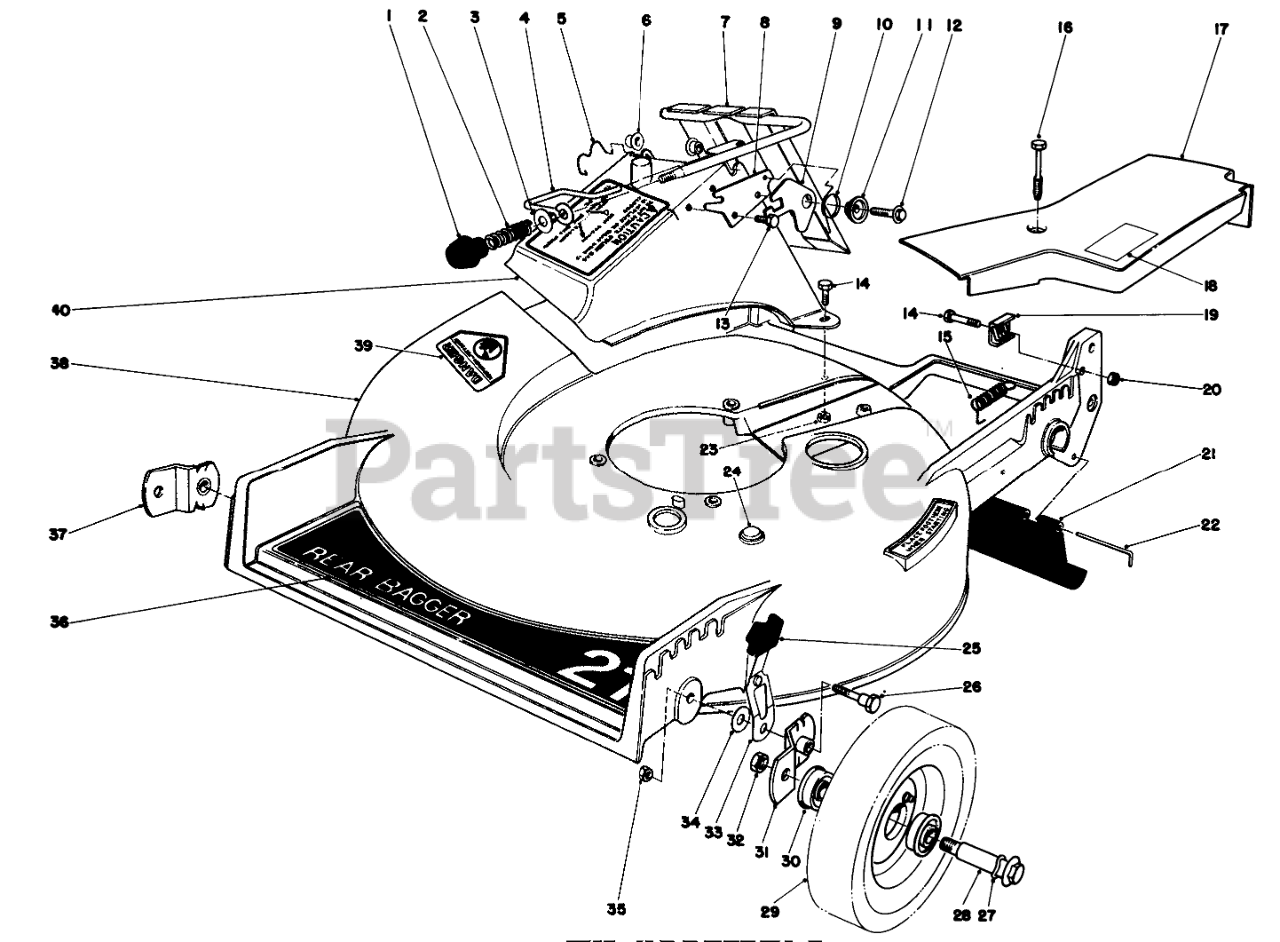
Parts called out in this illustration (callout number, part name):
2	Spring Compression
3	WASHER-FLAT
4	DOOR LATCH
5	DOOR RETAINER
6	BUSHING-NYLON
7	DOOR & HANDLE WA
8	DOOR LATCH PLATE
9	Latch-Door
10	Spring-Torsion
11	Latch Spacer
12	Screw
13	SCREW-HWH
14	SCREW-HH
15	IDLER SPRING
16	SCREW-HHFTF
17	Belt Cover
18	Sticker Grease
19	CLAMP-CABLE
20	NUT-JAM
21	SHIELD - TRAILING
22	Rod Shield
23	NUT-LOCK, NI
25	KNOB-ARM
26	PIVOT SCREW
27	SPRING WASHER
29	Wheel & Tire Assembly (Incl. Ref. #30)
30	BEARING-BALL
31	PIVOT ARM ASM A
32	Nut
33	Spring Arm
34	Washer
35	Nut
36	Decal-Deck
37	PIVOT ARM ASM B
38	Housing
39	DECAL-DANGER
40	DISCHARGE CHUTE B
